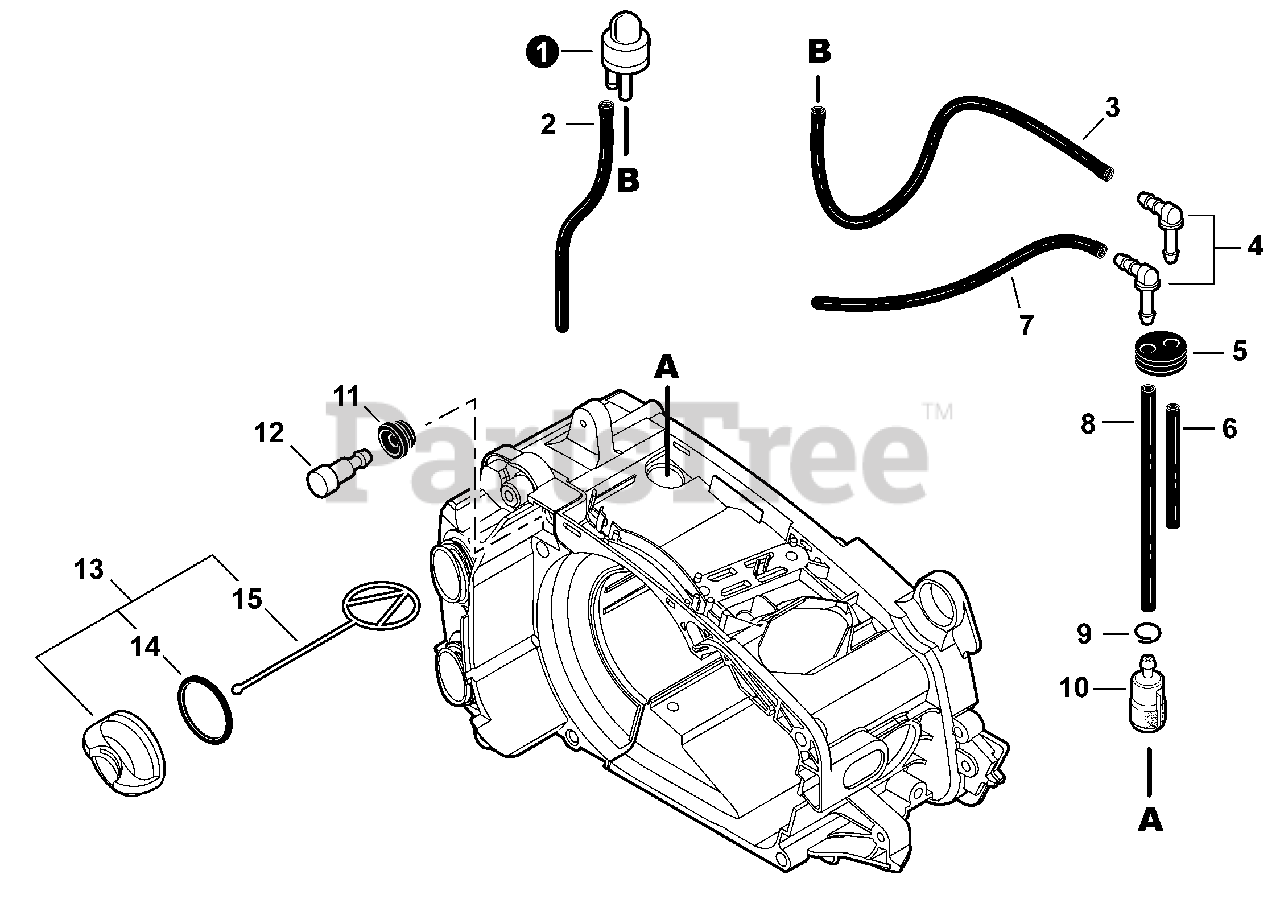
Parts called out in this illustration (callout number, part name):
1	BULB, PURGE
2	PIPE 2.4×5×180 - BLACK
3	PIPE 2.4×5×400 - BLACK
4	CONNECTOR, PIPE
5	GROMMET, FUEL
6	PIPE 2.4×5×15 - BLACK
7	PIPE 3×5×265 - BLACK
8	PIPE 3×5×140 - BLACK
9	CLIP Ø6
10	FILTER, FUEL
11	GROMMET, FUEL
12	VENT ASSY
13	CAP ASSY, FUEL
15	CONNECTOR, CAP L= 60 MM
